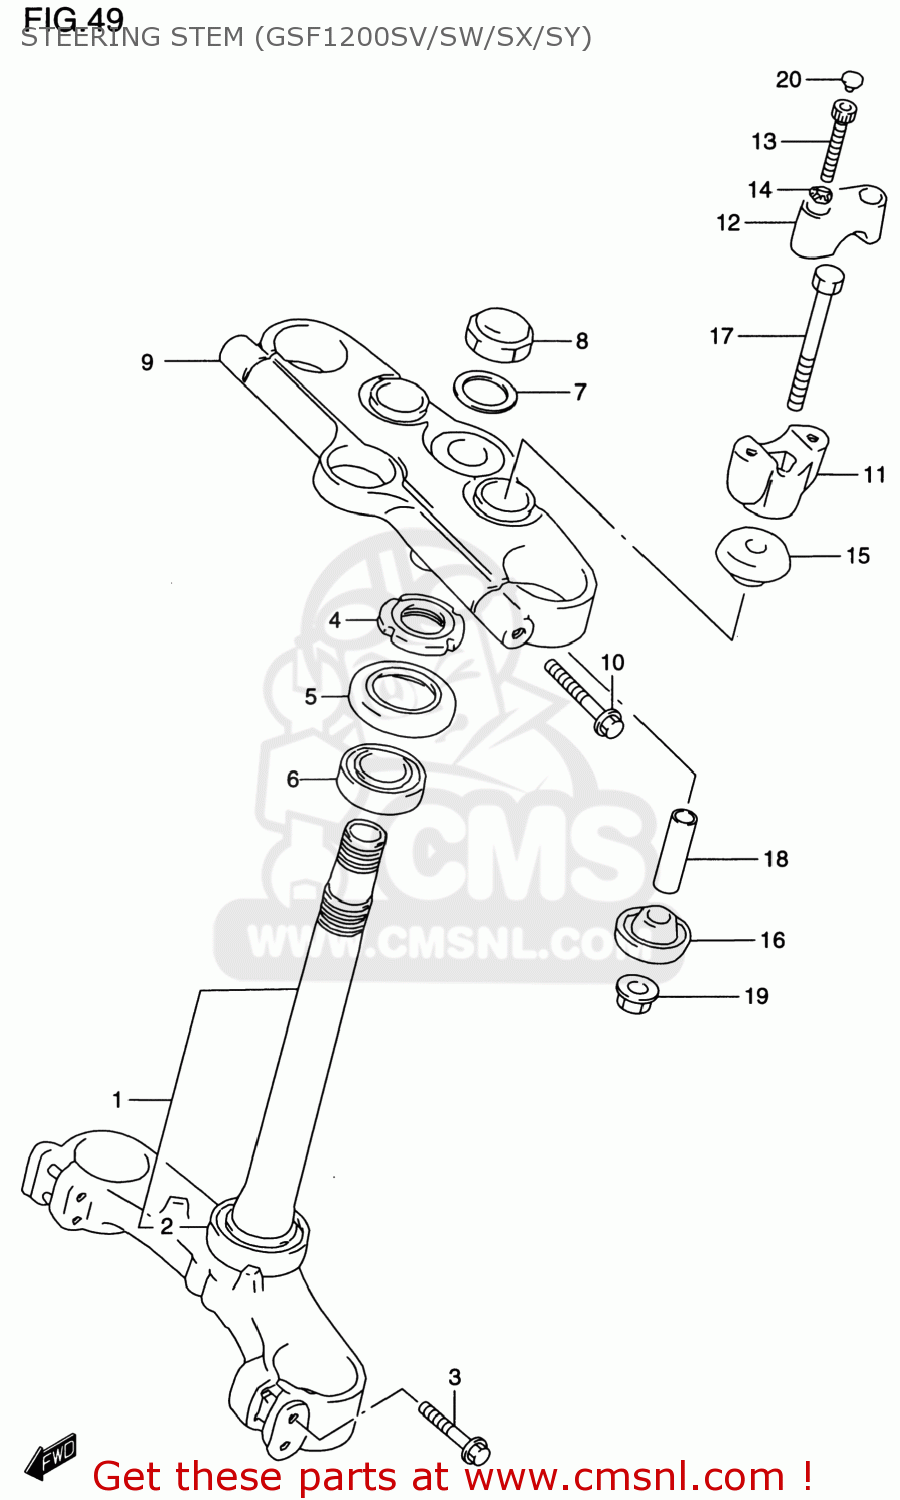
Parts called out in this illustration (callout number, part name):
1	STEM,STEERING
2	BEARING(30X55X17)
3	BOLT
4	NUT,STEERING STEM(25X44X10)
5	SEAL,STEERING UPR DUST
6	BEARING(25X47X15)
7	WASHER(22.5X32X1.6)
8	NUT,CAP
9	HEAD,STEERING STEM
10	BOLT
11	HOLDER,HANDLE UNDER
12	HOLDER,HANDLE UPR
13	BOLT
14	WASHER
15	CUSHION,RUBBER UPR
16	CUSHION,RUBBER UNDER
17	BOLT,HANDLE HOLDER(10X70)
18	SPACER
19	NUT
20	CAP(OD:11)
